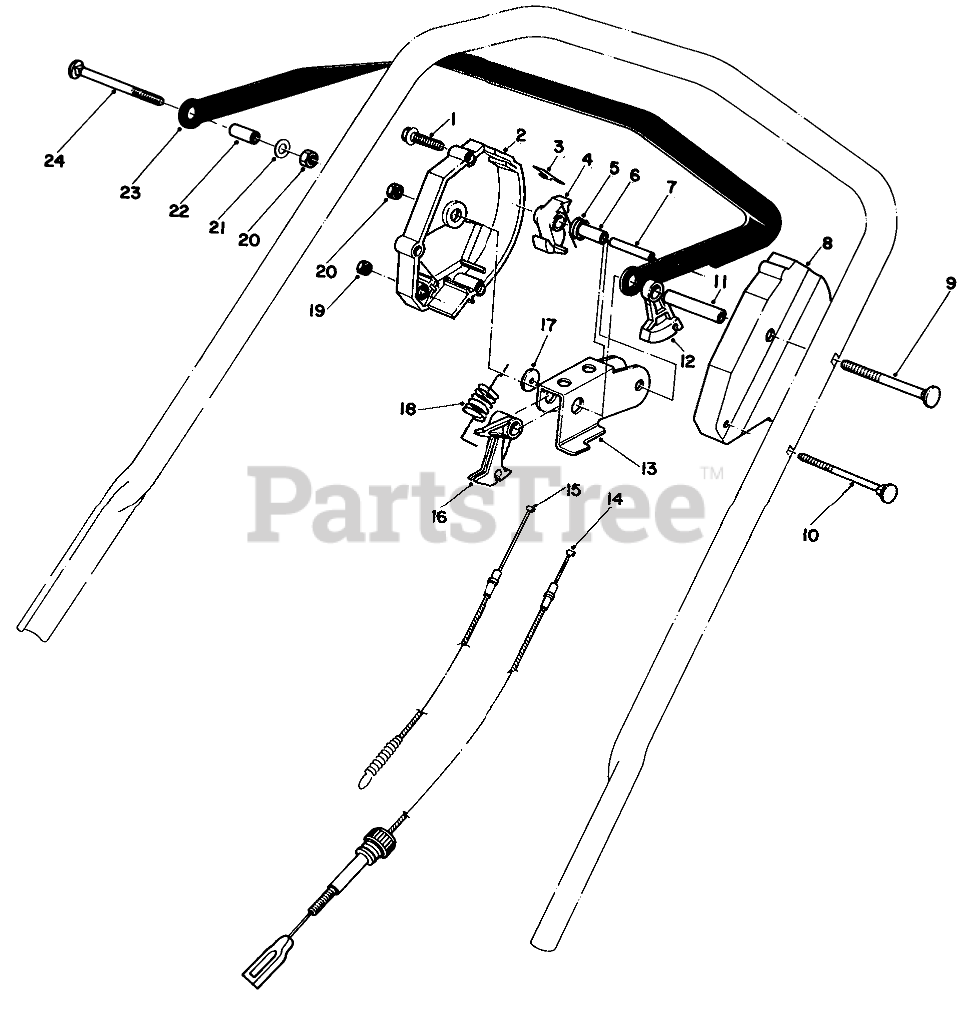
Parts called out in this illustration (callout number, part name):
1	SCREW-HWHTF
2	Housing Control R.H.
3	LEAF SPRING
4	HOOK-CONTROL
5	SPRING-TORSION
6	SPACER
7	PIN-ROLL, SLOTTED
8	HOUSING-CONTROL, LH
9	5/16-18 X 3 HNDLE SCREW
10	HANDLE SCREW
11	TUBING-SPACER
12	LEVER-TRACTION
13	Rocker
14	TRACTION CABLE
15	Cable-Clutch
16	LEVER-CABLE
17	PLASTIC WASHER
18	Spring-Extension
19	NUT-LOCK, NI
20	NUT-LOCK, NI
21	WASHER-PLAIN
22	Spacer
23	Bar-Control
24	5/16-18 X 2 HNDLE SCREW
